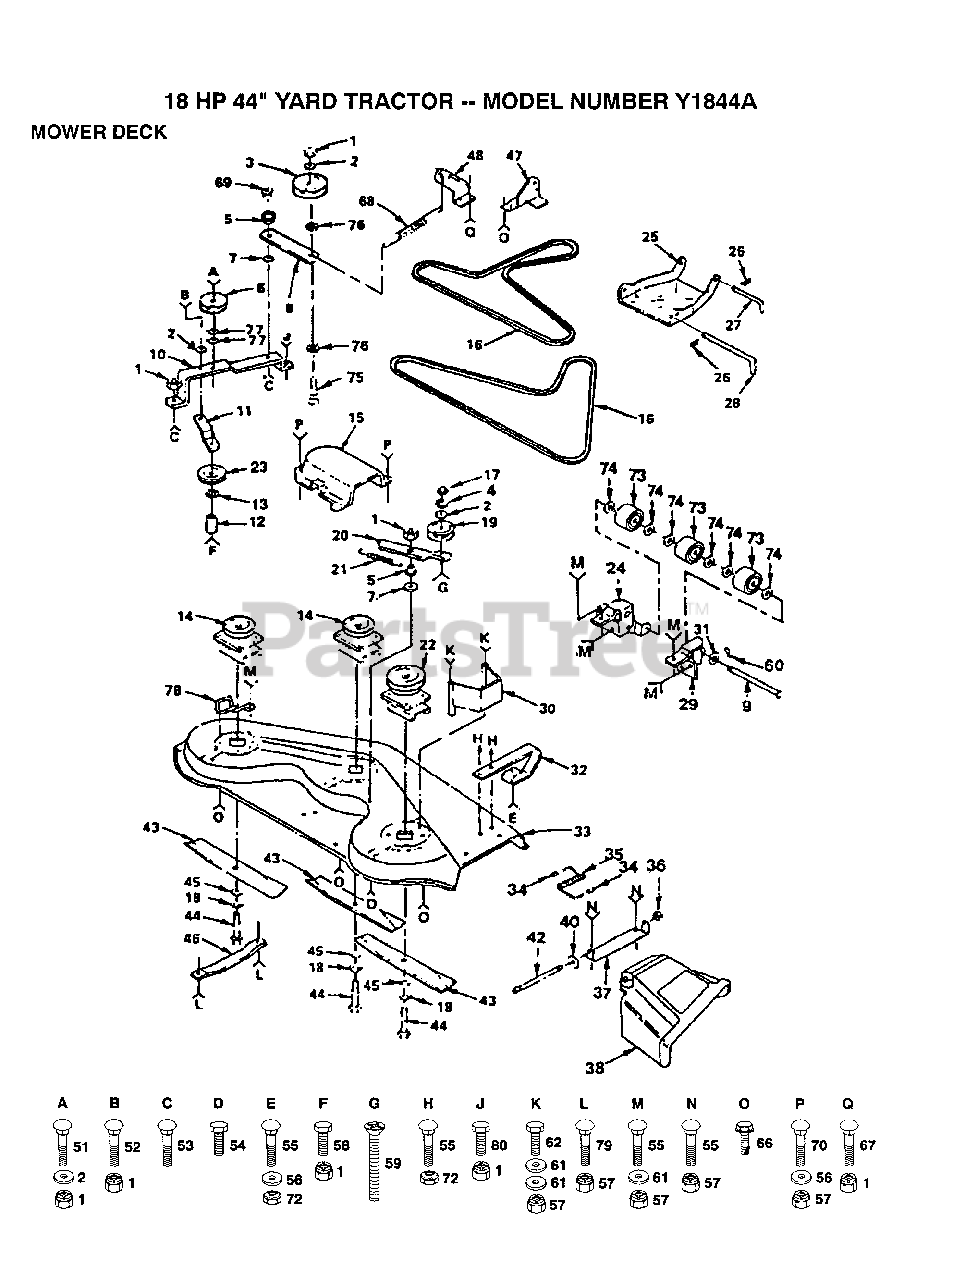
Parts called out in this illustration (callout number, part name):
2	WASHER
3	PULLEY IDLER
4	LOCKWASHER
5	SPACER RETAINER
6	IDLER-INSIDE T
7	"WASHER, WEAR LT"
8	ARM IDLER
9	PIVOT PIN T
10	"SUPPORT YT, BAR"
11	BRACE-IDLER YT
12	SPACER
13	WASHER
15	GUARD YT
16	BELT-V.79.1.MWR
17	NUT.HEX.3/8-16UNC
19	IDLER.FLAT.GTV
20	ARM-IDLER YT
22	JACKSHAFT
23	IDLER-FLAT T
24	BRACKET LH YTH
25	LINK.PARALLEL
26	SPRING.RETAINER
27	"ROD, FRT. PARAL T"
28	HINGE PIN T
29	BRACKET RH YTH
30	GUARD BELT HYT
34	CAP-SLEEVE LT
36	NUT PUSH M
38	DEFLECTOR SHIELD
40	WASHER
42	ROD-HINGE T
44	BOLT.3/8-24X1-1/2
45	WASHER
46	RUNNER-LH M
47	BRKT SUSP REAR RH
48	BRKT SUSP REAR LH
51	BOLT
53	BOLT
55	BOLT
56	WASHER
58	BOLT - HEX 3/8 - 16 X 3
59	SCREW YT
60	COTTER PIN
61	WASHER M
62	BOLT
66	SCREW
67	BOLT
68	"SPRING.EXT.8.5"""
69	LOCKNUT
73	ROLLER T
74	WASHER T
75	BOLT
76	WASHER
77	WASHER
78	BELT RETIANER
79	BOLT
80	BOLT
